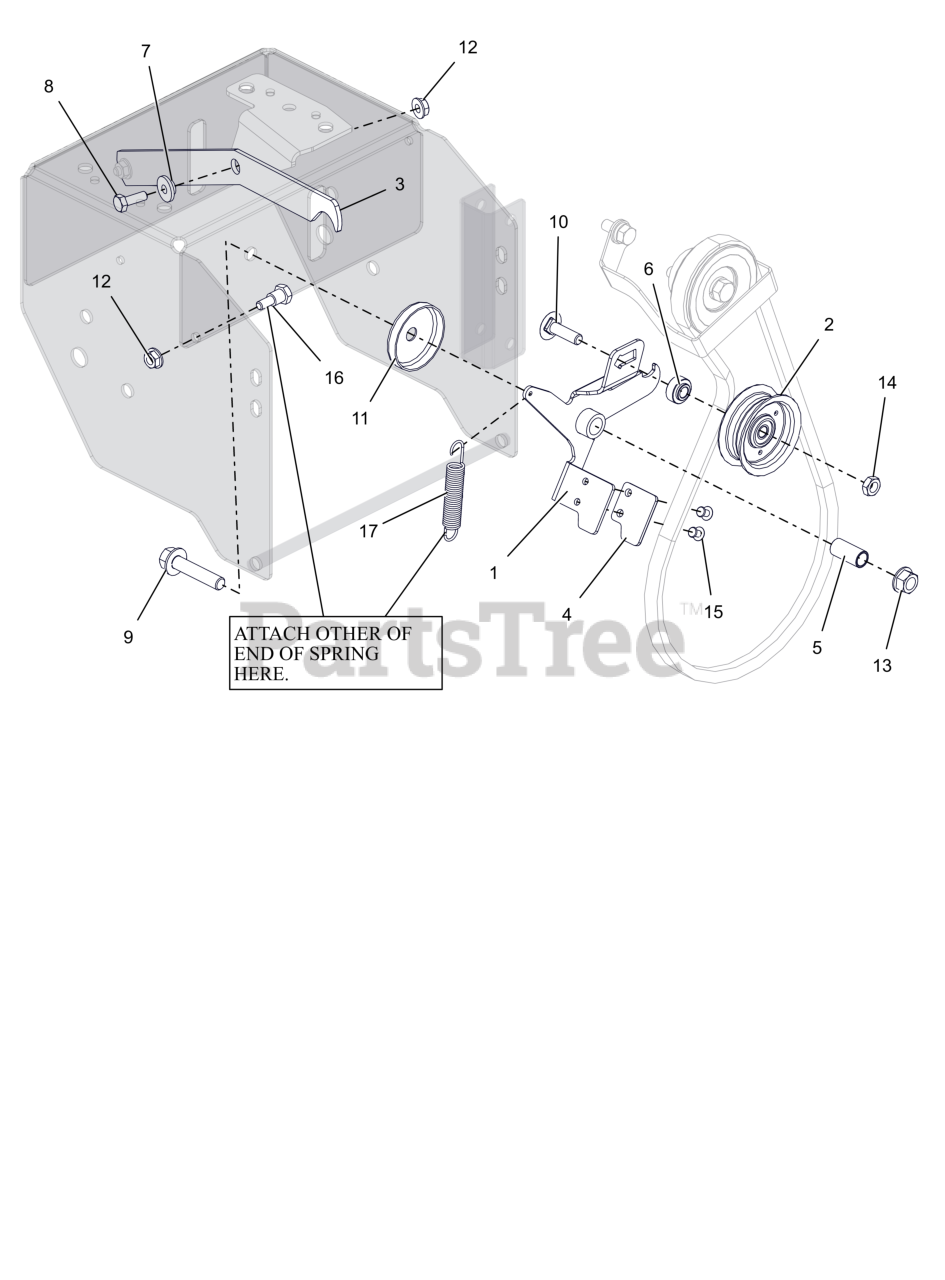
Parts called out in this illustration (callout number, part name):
1	WLDMT, IDLER ARM ATTACHMENT
2	IDLER, FLAT - 2.00"
3	LEVER, IDLER ARM ENGAGEMENT
4	PAD, BRAKE
5	BSHG-SLV .385X.500X1.045
6	SPCR, BRG .315X.500X.358X.281
7	BSHG-FLG .265X.437X.250X.750
8	BLT, HEX .25-20X.75 G5 ZCC
9	BLT,HEX-FLG .38-16X1.75 G5 ZCC
10	BLT, RHSSN .31-18X1.125 G5 ZCC
11	SHIELD, AXLE BEARING
12	NUT-LK-CTR-FLG .25-20 ZC120
13	NUT-LK-CTR-FLG .375-16 GF ZCC
14	NUT-LK-CTR-JAM .312-18 GB ZCC
15	RVT, POP .1875 ZCC
16	BOLT, SHLDR -.375 X .375 X .25-20
17	SPRING,EXT,.061X.50X3.0
